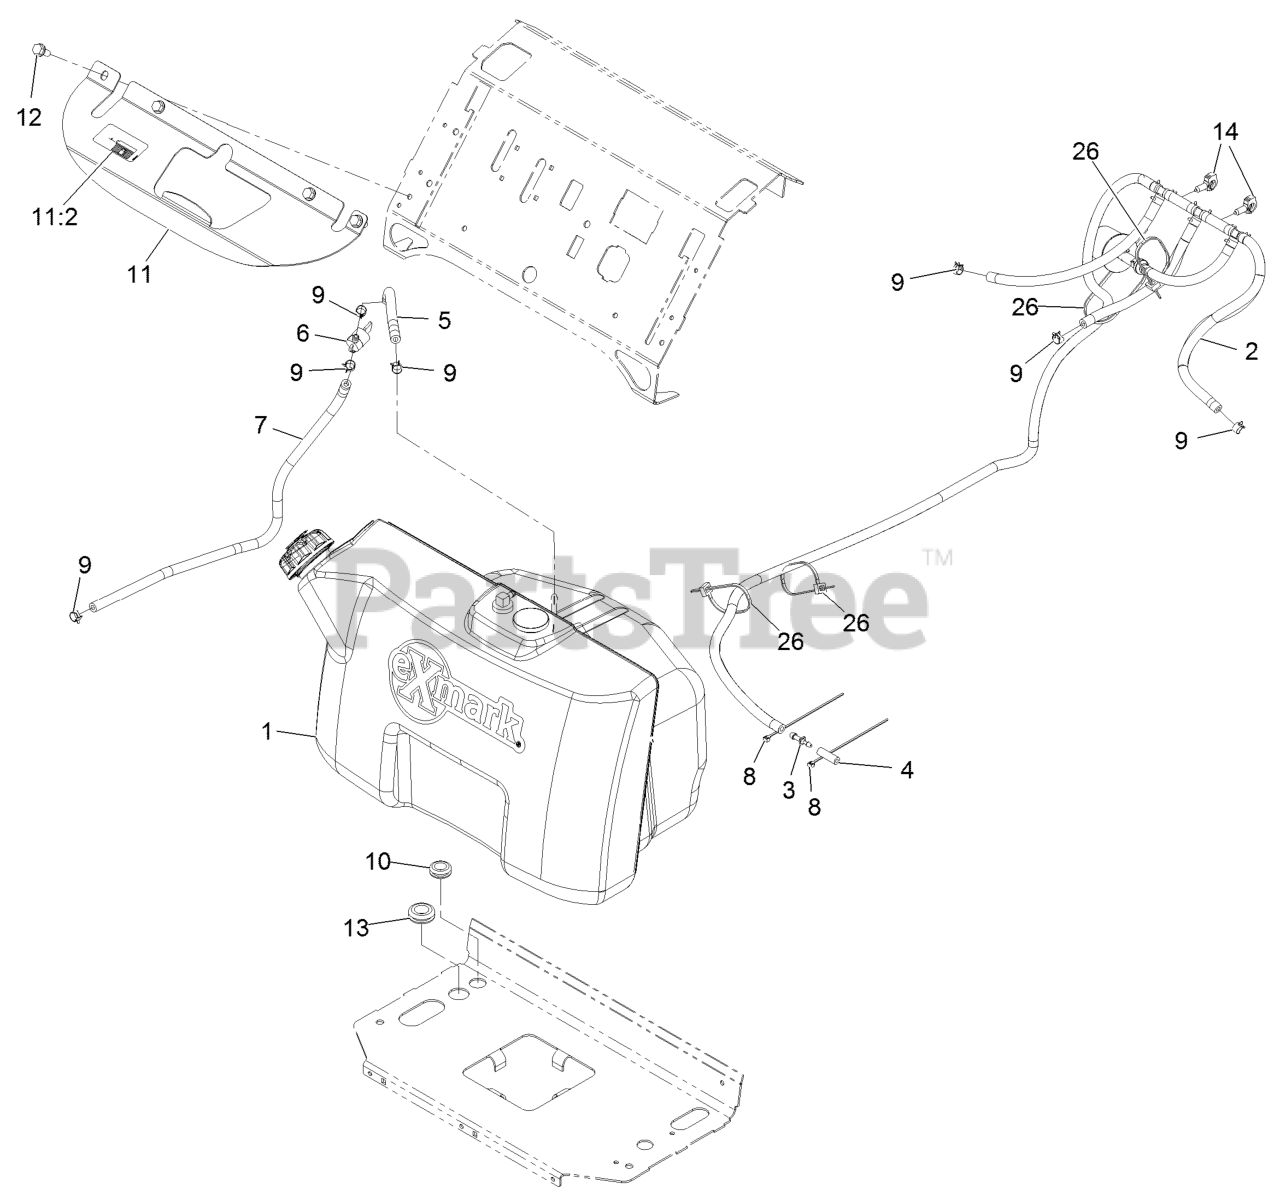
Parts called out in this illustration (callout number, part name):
2	VENT ASM
3	FITTING-STRAIGHT
4	HOSE-FUEL
5	HOSE-FUEL
6	VALVE-FUEL
7	HOSE-FUEL
8	TIE-CABLE
9	CLAMP-HOSE
10	GROMMET
11	BRACKET-TANK
11:2	DECAL-FILL, FUEL
12	SCREW-THD ROLL, HWH
13	GROMMET
14	CLIP-HARNESS
26	TIE-CABLE
